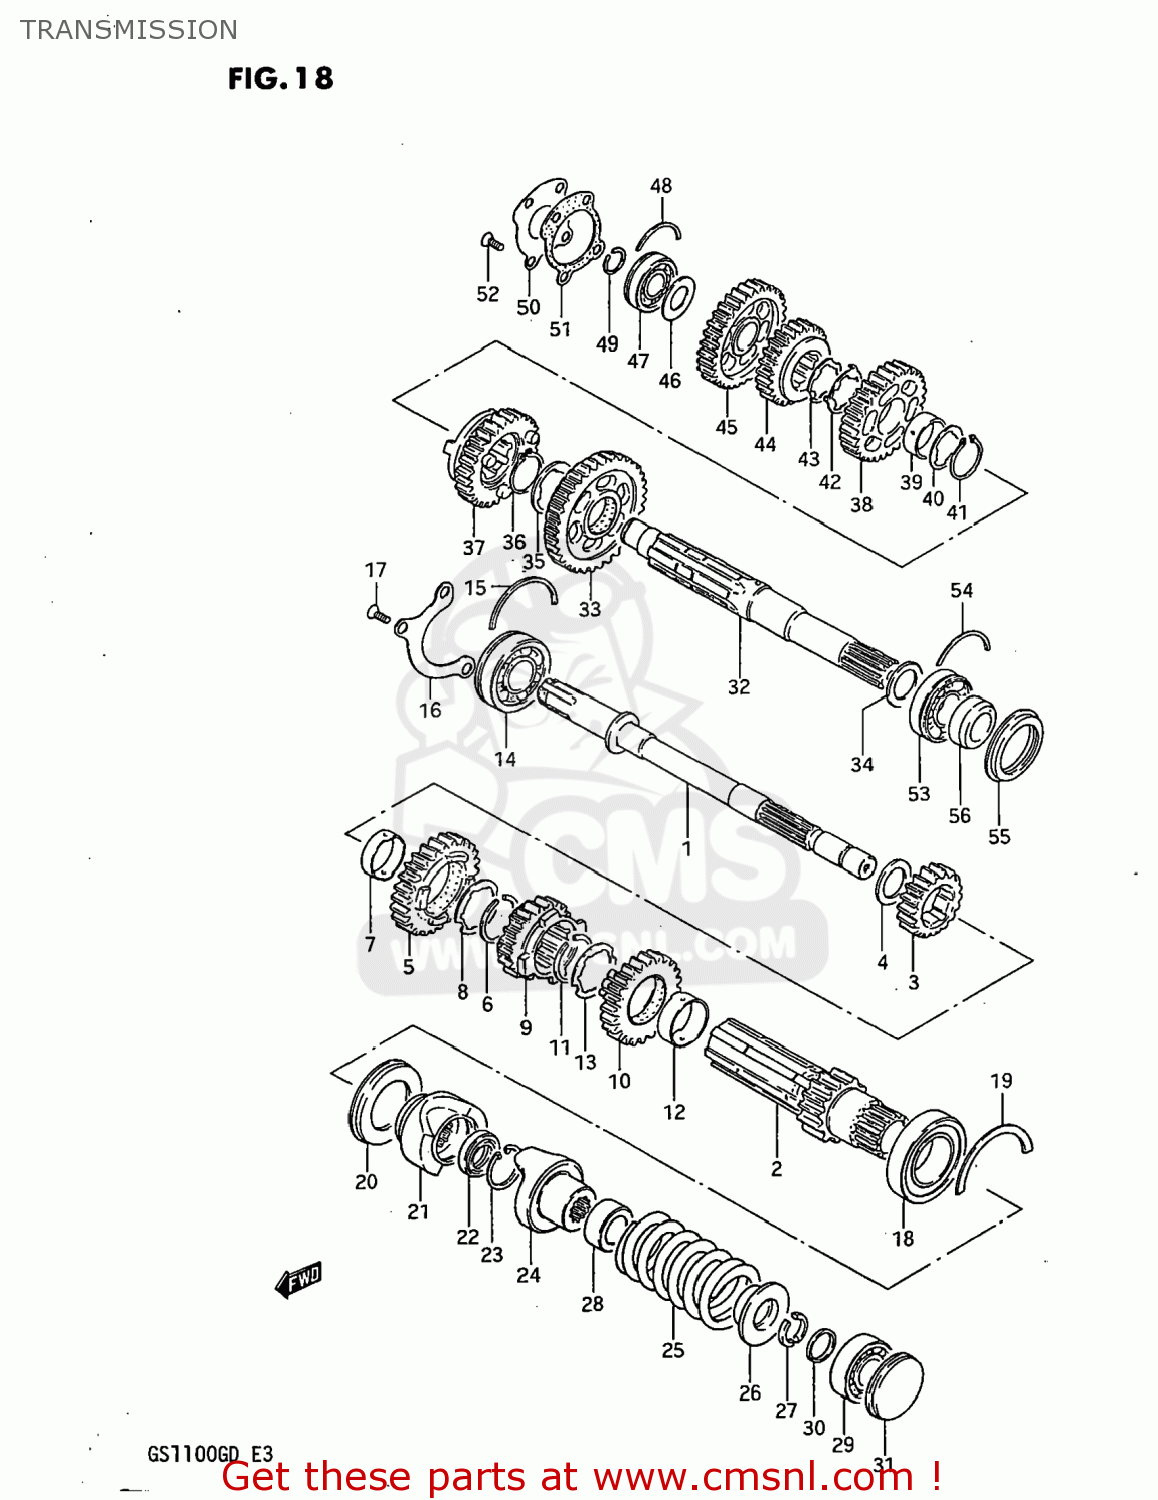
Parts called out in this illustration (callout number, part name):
1	SHAFT,COUNTER
2	SHAFT,OUTER COUNTER
3	GEAR,SECOND DRIVE
4	WASHER (21X35X2)
5	GEAR,5TH DRIVE(NT:26)
6	RING,SNAP
7	SPACER,DRIVE GEAR
8	LOCK WASHER,5TH DR GEAR SPACER
9	GEAR,THIRD DRIVE
10	GEAR,FOURTH DRIVE
11	RING,SNAP
12	SPACER,DRIVE GEAR
13	LOCK WASHER,5TH DR GEAR SPACER
14	BEARING(25X62X17)
15	C-RING
16	RETAINER,CNTR SHAFT BEARING
17	SCREW
18	BALL BEARING 32X58X13
19	C-RING
20	SEAL,OIL(40X58X7)
21	DOG,OUTPUT CAM
22	SEAL,OIL(20.6X31X6)
23	CIRCLIP
24	DOG,INPUT CAM
25	SPRING
26	STOPPER,CAM DOG SLIDING
27	STOPPER,CAM DOG
28	GUIDE,CAM DOG SPRING
29	BEARING
30	SPACER (17X21X3.5)
31	PLUG
32	SHAFT,DRIVE
33	GEAR,FIRST DRIVEN
34	WASHER, LH
35	WASHER,LOCK
36	CIRCLIP
37	GEAR,FOURTH DRIVEN
38	GEAR,THIRD DRIVEN
39	BUSH,3RD DRIVEN GEAR
40	WASHER,LOCK
41	CIRCLIP
42	WASHER
43	WASHER,LOCK
44	GEAR,FIFTH DRIVEN
45	GEAR,SECOND DRIVEN
46	WASHER
47	BEARING(20X47X14)
48	C RING
49	CIRCLIP
50	PLATE,DRIVESHAFT
51	GASKET,DRIVESHAFT PLATE (MCA)
52	SCREW
53	BEARING
54	C RING
55	SEAL,OIL(35X52X6)
56	SPACER,DRIVESHAFT,LEFT
